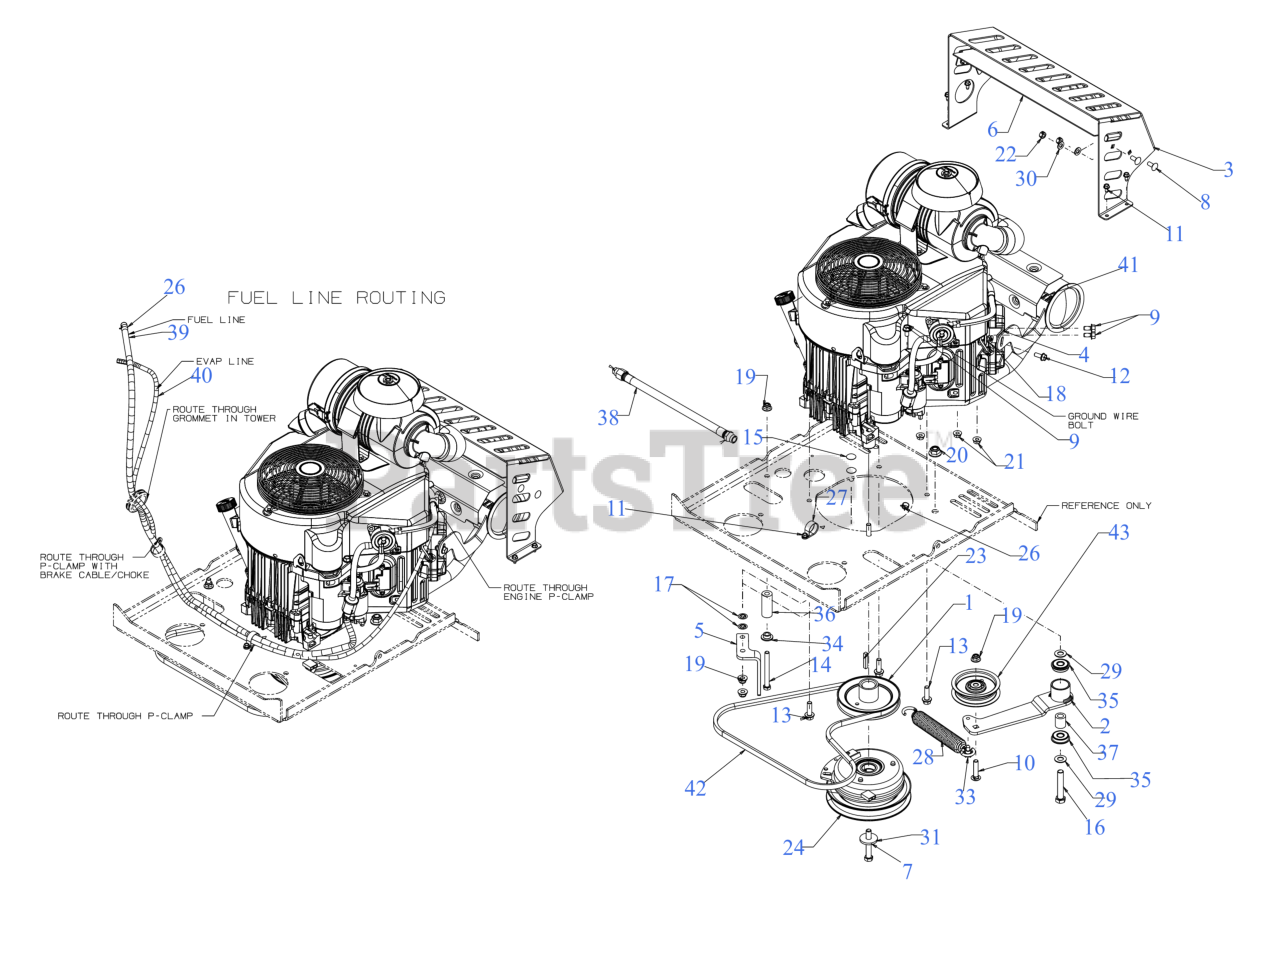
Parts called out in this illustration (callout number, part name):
1	PULLEY
2	IDLER BRACKET ASSEMBLY
3	MUFFLER SHIELD
4	MUFFLER MOUNTING BRACKET
5	CLUTCH BRACKET
6	INNER MUFFLER SHIELD
7	SCREW 7/16-20:2.75 GR5
8	CARRIAGE BOLT 5/16-18 x .75
9	SCREW M8 x 1.25 x 16MM GR8.8
10	CARRIAGE BOLT 3/8-16 x 1.75 GR5
11	SCREW 1/4-20 X.500
12	SCREW 5/16-18 x .750 GR8
13	SCREW 3/8-16 x 1.25 GR5
14	SCREW 3/8-16 x 3.50 GR5
15	CARRIAGE BOLT 3/8-16 x 1.00 GR5
16	SCREW 1/2-13 x 2.75 GR5
18	FLANGE LOCK NUT 5/16-18
21	HEX FLANGE NUT
22	HEX NUT LOCK CENTER
23	SQUARE KEY 1/4 x 1.50
24	ELECTRIC PTO CLUTCH
26	HOSE CLAMP 1/20
27	DRAIN HOSE CLAMP
28	SPRING 1.25" DIA x 8.5" LONG
29	FLAT WASHER .510X.995
30	FLAT WASHER
31	FLAT WASHER .45 x 1.5 x .172 HT
33	SHOULDER SCREW .43X.29X5/16-18 TT
34	SHOULDER SPACER
35	ROLLER BEARING .5X1.37X.44
36	SPACER .41 x .875 x 2.19
37	SPACER 0.51 x 0.88 x 1.00
38	OIL DRAIN HOSE
39	FUEL HOSE LOW PERMEATION 54"
40	VENT HOSE 3/16 ID 70"LG
41	MUFFLER
42	BELT SEC A x 51.18
43	FLAT IDLER PULLEY 3.5
